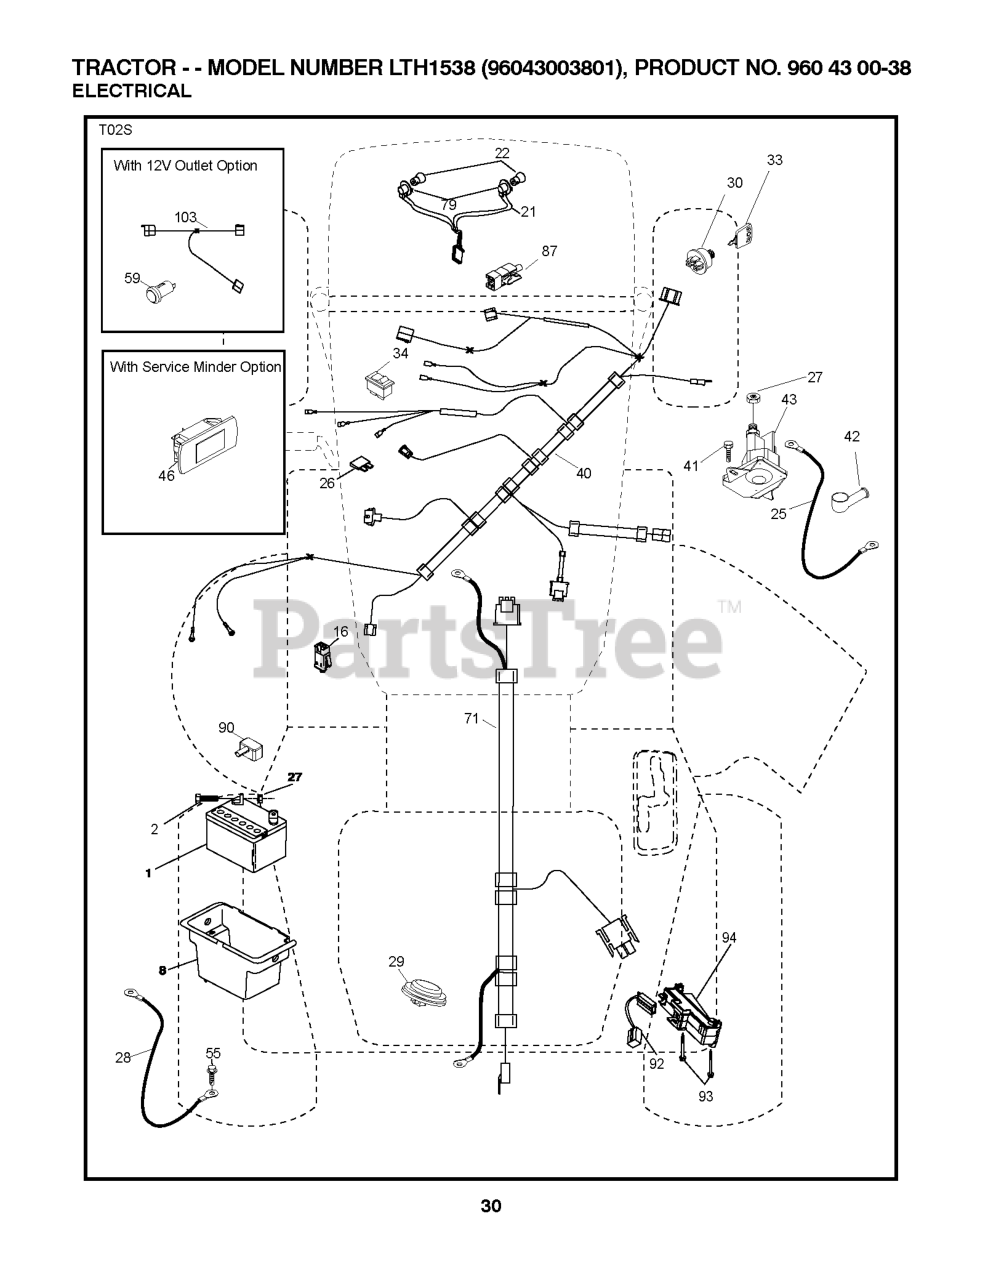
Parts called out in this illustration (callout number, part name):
1	Battery 12 Volt 25 Amp
2	BOLT.HEX.1/4.X.3/4.DICHROMATE
8	BOX.BATTERY.MNT.REAR.L
16	SWITCH INTERLOOK PUSH-IN
21	HARNESS.LIGHT W/4152J BULBS
25	CABLE.STARTER.6GA.RED.
26	FUSE 20AMP
27	NUT
28	CABLE.BLACK.18"REAR.BA
29	SWITCH.SEAT.DELTA.OPC.
30	SWITCH.IGN.DELTA.W.LGH.ROS
33	KEY MLD GEN DELTA
40	HARNESS IGN. DASH
41	SCREW
42	TERMINAL COVER
43	SOLENOID.W/BRASS.PLUNGER
55	SCREW 5/16"
71	HARNESS.IGN.CHASS.TEX.REAR.BAT
79	BULB HOLDER ASM.
87	SWITCH.INTRLCK.CLUTCH.
90	COVER, TERMINAL BATTERY
92	HARNESS.PIGTAIL.CONSLE
93	SCREW.PLASTITE
94	MODULE.REVERSE.ROS
